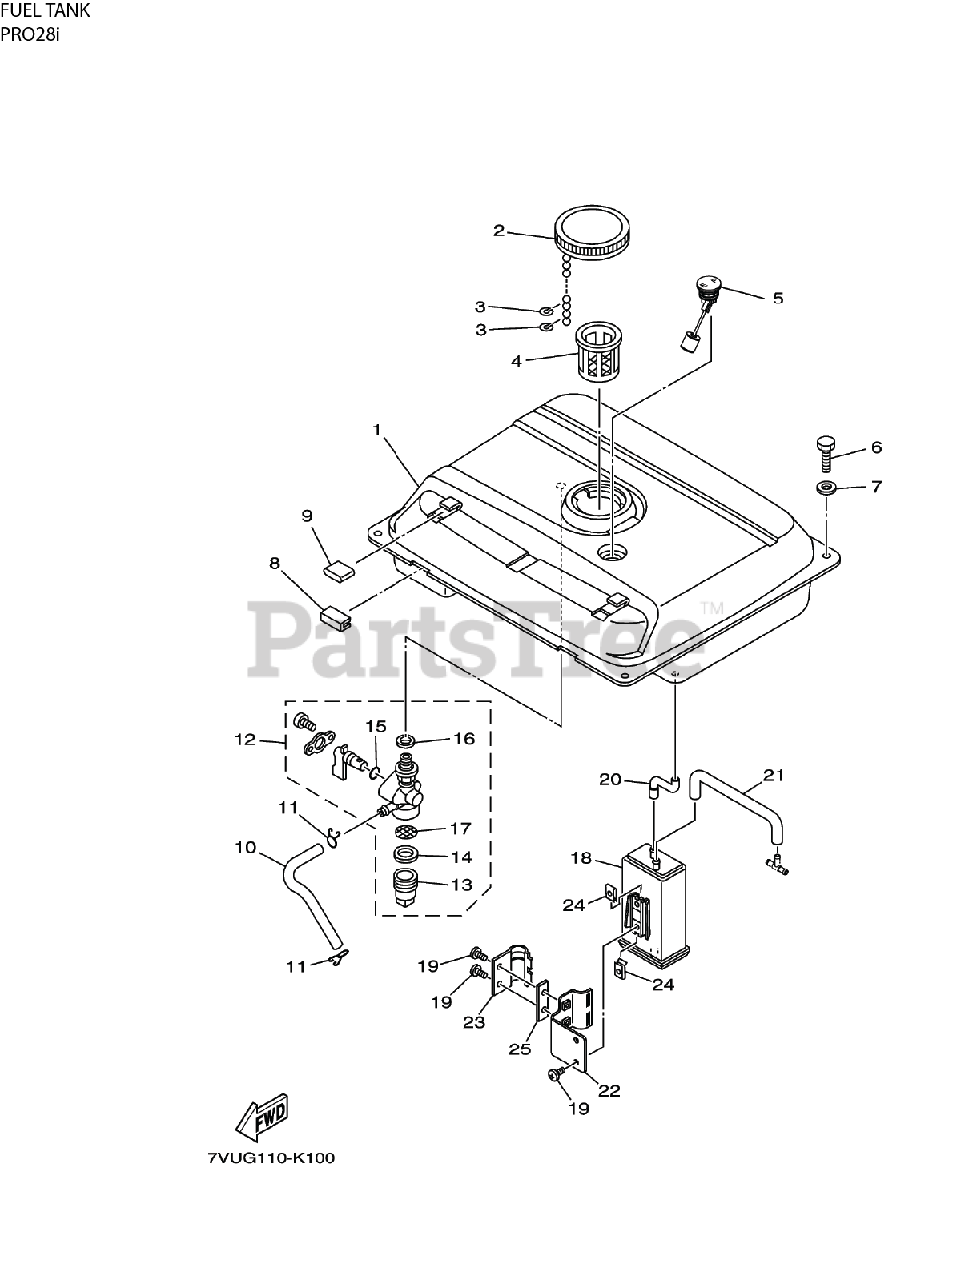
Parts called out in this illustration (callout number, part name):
1	TANK, FUEL COMP
2	CAP ASSEMBLY
4	FILTER, STRAINER
5	FUEL LEVEL GAUGE ASSEMBLY
6	SCREW - BOLT
7	WASHER PLAIN
8	DAMPER, LOCATING
9	DAMPER, LOCATING
10	FUEL HOSE, LOW PERMEATION
11	CLAMP - CLIP
12	VALVE, FUEL COCK ASSEMBLY
13	BOWL, FUEL - CUP FILTER
15	O-RING, SEAL, COCK
17	SCREEN - NET, FILTER
18	CANISTER, CARBON
22	BRACKET, CLAMP
23	BRACKET, CLAMP
